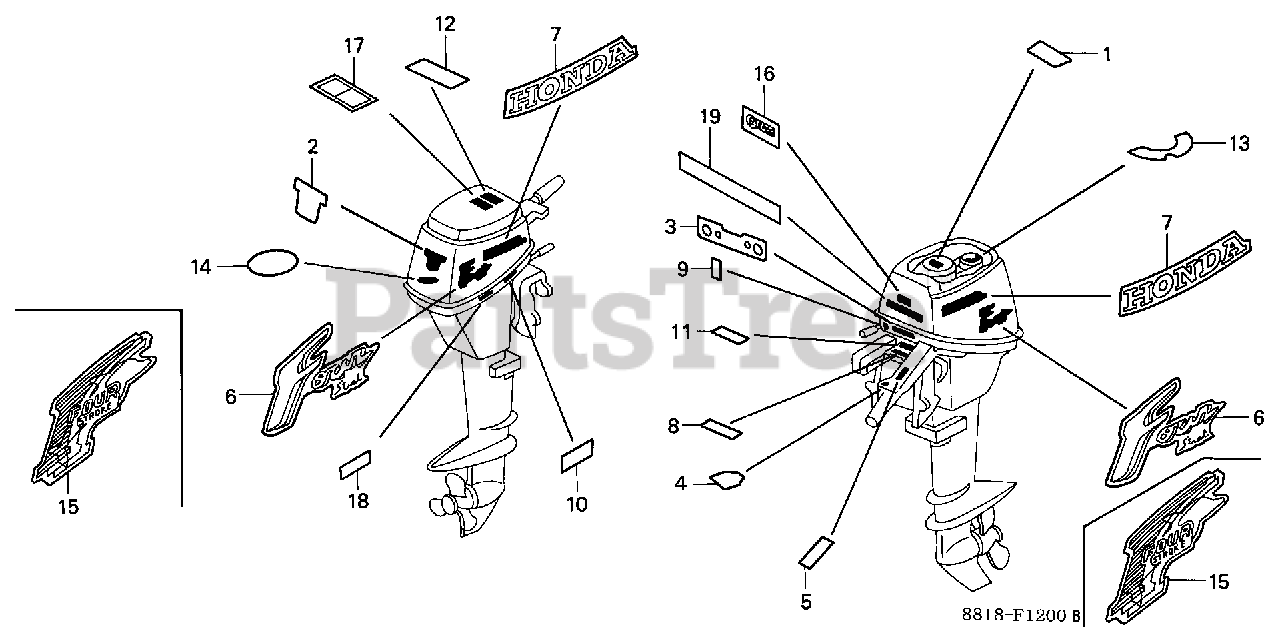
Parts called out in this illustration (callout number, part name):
1	MARK, RECOIL STARTER CAUTION
2	MARK, RR. (8)
3	LABEL, INDICATION (E)
4	MARK, EMERGENCY SWITCH INDICATION (ENGLISH)
5	MARK, SPARE CLIP (ENGLISH)
7	MARK, SIDE STRIPE (HONDA)
8	LABEL, SPECIFICATION
9	MARK, CHANGE
10	LABEL, CAUTION OIL (E)
12	LABEL, CAUTION OPERATOR (ENGLISH)
13	MARK, POINT
15	MARK, SIDE
16	MARK (E-SPEC)
17	MARK, OPERATOR CAUTION
18	LABEL, STORING CAUTION (ENGLISH)
19	MARK, FUEL CAUTION
